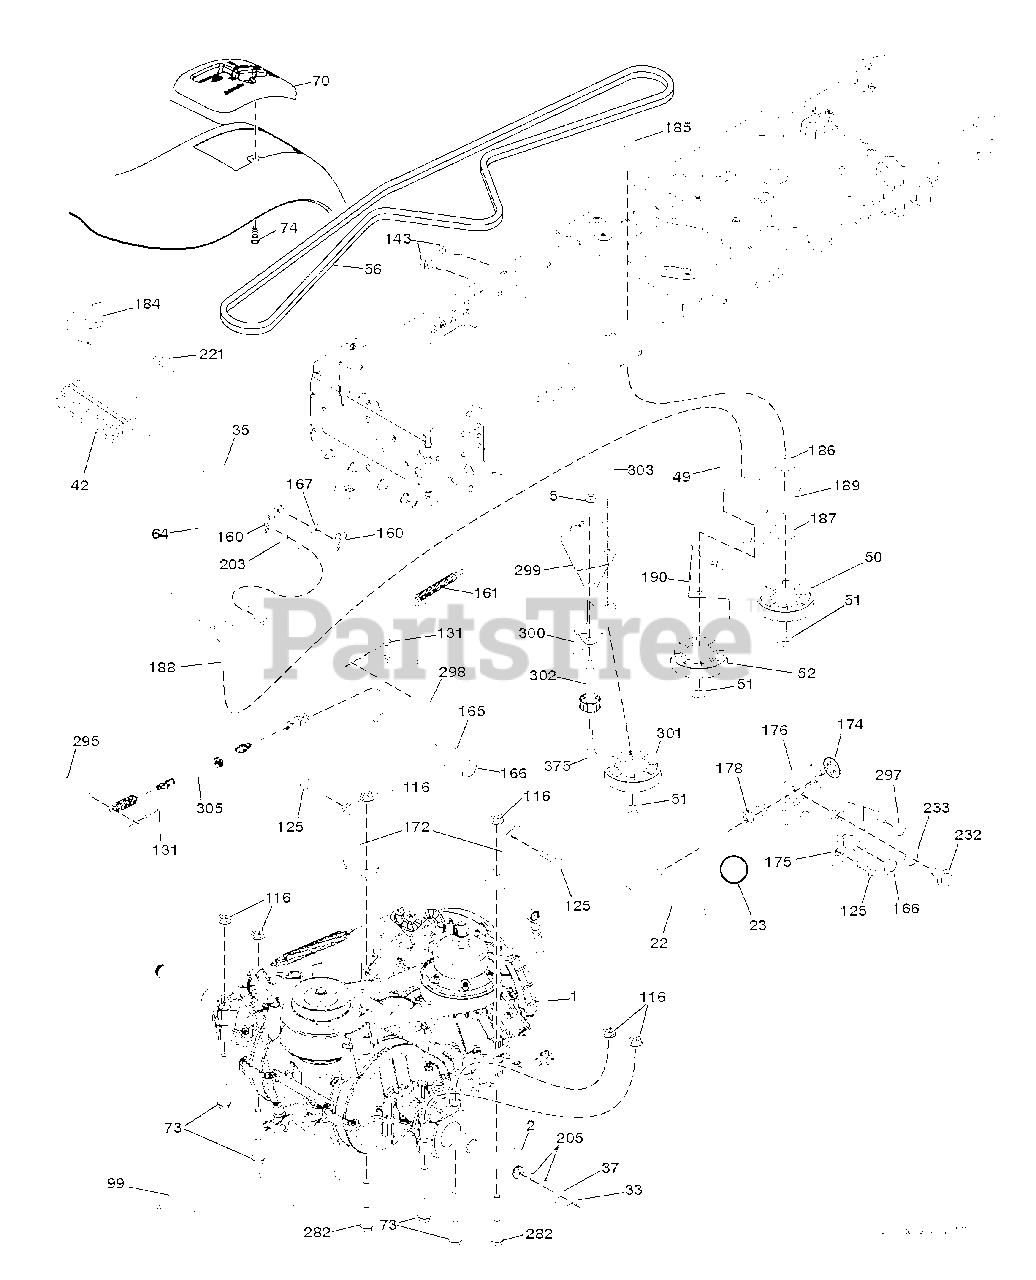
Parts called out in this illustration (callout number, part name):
2	SQUARE KEY
5	LOCKNUT
22	ROD.SHIFT.LT.TEX.VARIATOR
23	KNOB T (1/2-HOLE)
33	E-RING LT
35	ROD.BRAKE.PARKING.LT.T
49	BOLT
50	IDLER.FLAT.910.OFFSET
51	NUT LOCK FLG 3/8-16 UNC
52	IDLER.V-GROOVE.910.OFFSET
56	BELT.DRIVE.MOWER.TEX.42"
64	SHAFT.ASM.PEDAL.BRAKE.
70	CONSOLE.AUTO.VARIATOR.BLACK
73	BOLT HEX 5/16-18 GR 5
74	SCREW.HI-LO.CONSOLE
99	ROD.BYPASS.VARIATOR
116	NUT LOCK HEX FLANGE 5/16-18
125	SCREW
143	SCREW LT
160	RETAINER CLIP
161	SPRING, RETURN LT
165	BUSHING.SHAFT.BRAKE.HAND
166	NUT.PUSH.625
167	LATCH.BRAKE.SPRING
172	STRAP.TORQUE.VARIATOR
174	NUT.PUSH.500.2006
175	SHAFT.ASM.SHIFT.VARIATOR
176	ARM.CLEVIS.ROD.SHIFT
178	SPRING.SHIFT.GT2006
184	HANDLE.PARKING.BRAKE.LTTEX.667
186	SPACER.RETAINER
187	WASHER 12/32X2X10GA
188	LINK.CLUTCH.GROUND.DRIVE
189	BELLCRANK.GROUND.DRIVE.TEX.
190	KEEPER.BELLCRANK.DRIVE
203	WASHER
221	RETAINER.SPRING.CLIP.H
232	BOLT FIN HEX 7/16-14 X 1
233	WASHER SERRATED
282	BOLT HEX FLGHD 5/16-18X3 GR. 5
295	PIN.CLEVIS.183
297	NUT.PUSH.1/4
298	PIN.CLEVIS.CBL.BRK.VARIATOR.TX
299	BRACKET.MOUNT.IDLERS
300	KEEPER.IDLERS.REAR.VARIATOR
301	PULLEY.IDLER.V-GROOVE
302	RB PULLEY.IDLER.FLAT.2.0"OD RP
303	BOLT CARRIAGE
305	CABLE.BRAKE.VARIATOR.TEX
